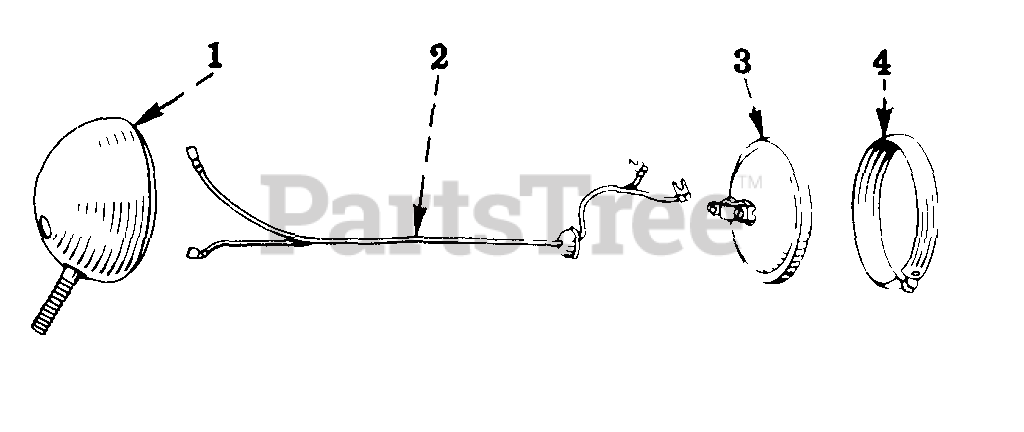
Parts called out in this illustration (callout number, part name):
1	BODY, LIGHT
2	WIRE ASSY
3	UNIT SEALED BEAM 6 VOLT
4	MOULDING ASSY, DIETZ
4	MOULDING ASSY. GUIDE
